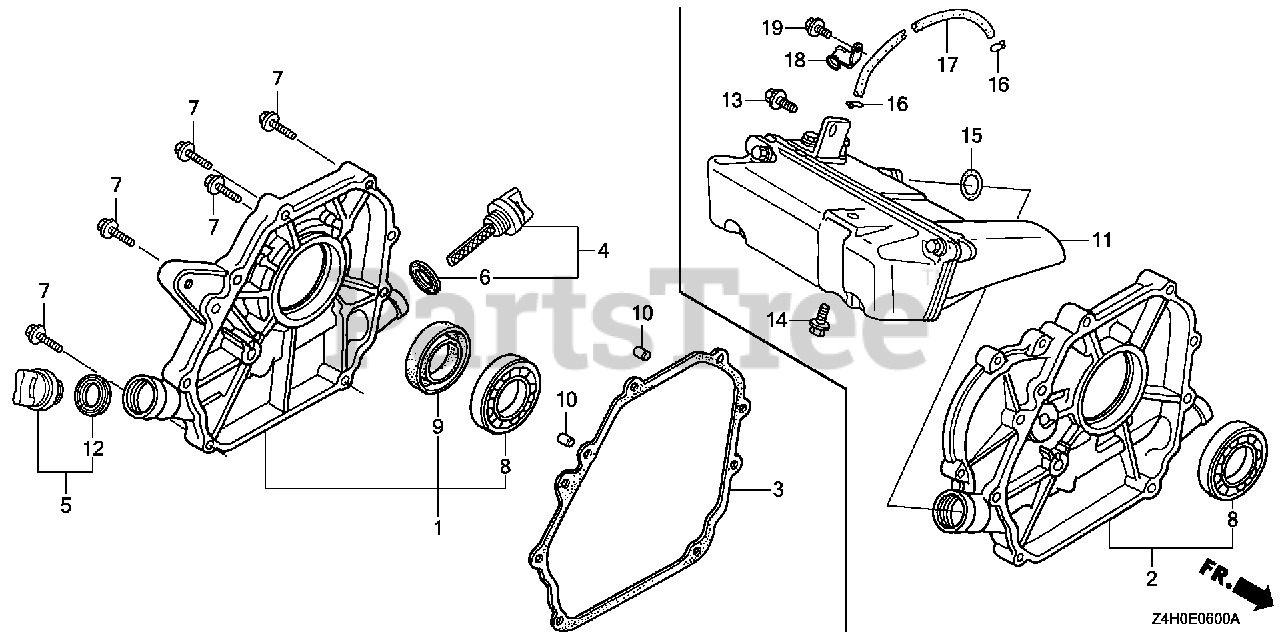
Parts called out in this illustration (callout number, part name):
1	COVER ASSY., CRANKCASE
3	GASKET, CASE COVER
4	CAP ASSY., OIL FILLER (GAUGE)(GRAY)
5	CAP ASSY., OIL FILLER (BLACK)
6	GASKET, OIL FILLER CAP
7	BOLT, FLANGE (6X28) (CT200)
8	BEARING, RADIAL BALL
9	OIL SEAL (22X41X6)
10	PIN, DOWEL (8X14)
12	GASKET, OIL FILLER CAP
